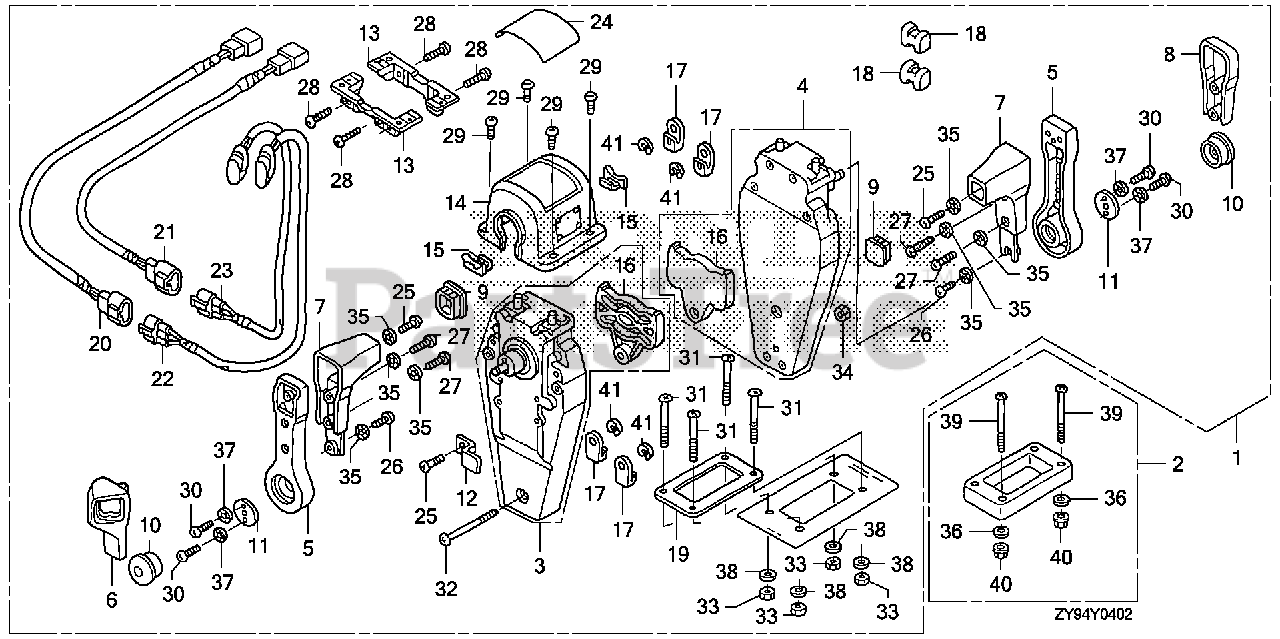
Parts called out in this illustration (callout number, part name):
1	BOX KIT, R. REMOTE CONTROL (TOP MOUNT DUAL)
2	SPACER KIT, REMOTE CONTROL BOX (TOP MOUNT DUAL)
3	HOUSING ASSY., L. (INNER) (TOP MOUNT)
4	HOUSING ASSY., R. (INNER) (TOP MOUNT)
5	HANDLE, REMOTE CONTROL
6	COVER, L. GRIP
7	GRIP, REMOTE CONTROL HANDLE
8	COVER, DUAL GRIP
9	CAP, GRIP
10	BUTTON, THROTTLE
11	PLATE, HANDLE
12	PLATE, CABLE CLAMP
13	BRACKET, REMOTE CONTROL HOUSING
14	HOUSING, DUAL REMOTE CONTROL BOX
15	HOUSING, LEAD
16	PLATE, DWELL
17	TERMINAL, CABLE
18	SPACER, CABLE CLAMP
19	GASKET, DUAL
20	SUB-HARNESS ASSY., POWER TRIM-TILT (A)
21	SUB-HARNESS ASSY., POWER TRIM-TILT (B)
22	SWITCH ASSY., POWER TRIM-TILT (A)
23	SWITCH ASSY., POWER TRIM-TILT
24	MARK, REMOTE CONTROL (DUAL)
25	SCREW, PAN (5X16)
26	SCREW, PAN (5X10)
27	SCREW, PAN (5X20)
28	SCREW, PAN (5X18)
29	SCREW, PAN (4X10)
30	SCREW, PAN (6X18)
31	SCREW, PAN (5X40)
32	SCREW, PAN (5X55)
33	NUT, HEX. (5MM)
34	NUT, HEX. (5MM)
35	WASHER, LOCK (5MM)
36	WASHER, PLAIN (5MM)
37	WASHER, LOCK (6MM)
38	WASHER, PLAIN (5MM)
39	SCREW, PAN (5X65)
40	NUT, HEX. (5MM)
41	E-RING (6MM)
